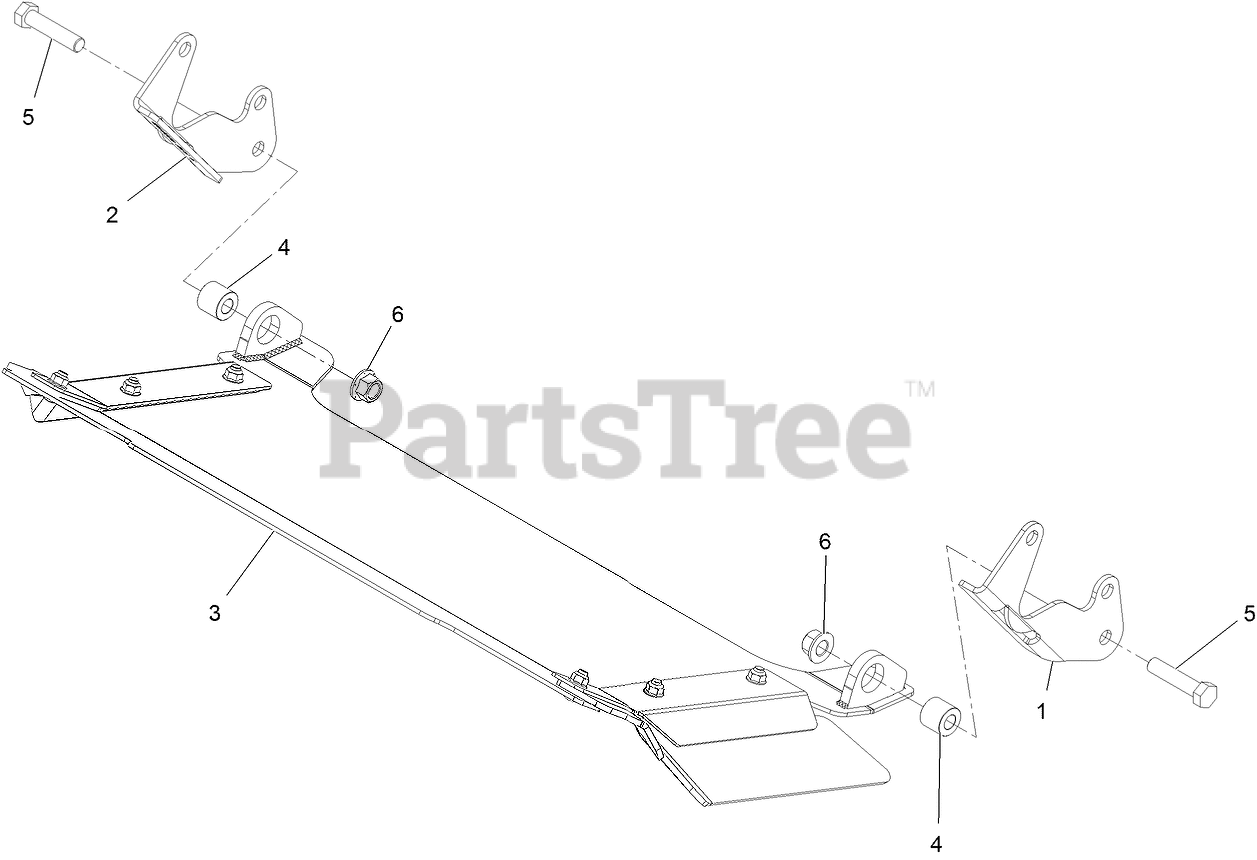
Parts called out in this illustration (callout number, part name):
1	BRACKET-DISCHARGE MOUNT,
2	BRACKET-DISCHARGE MOUNT,
3	DISCHARGE TUNNEL ASM
4	BUSHING-SLEEVE
5	SCREW-HH
6	Nut-Lock 1/2-13
